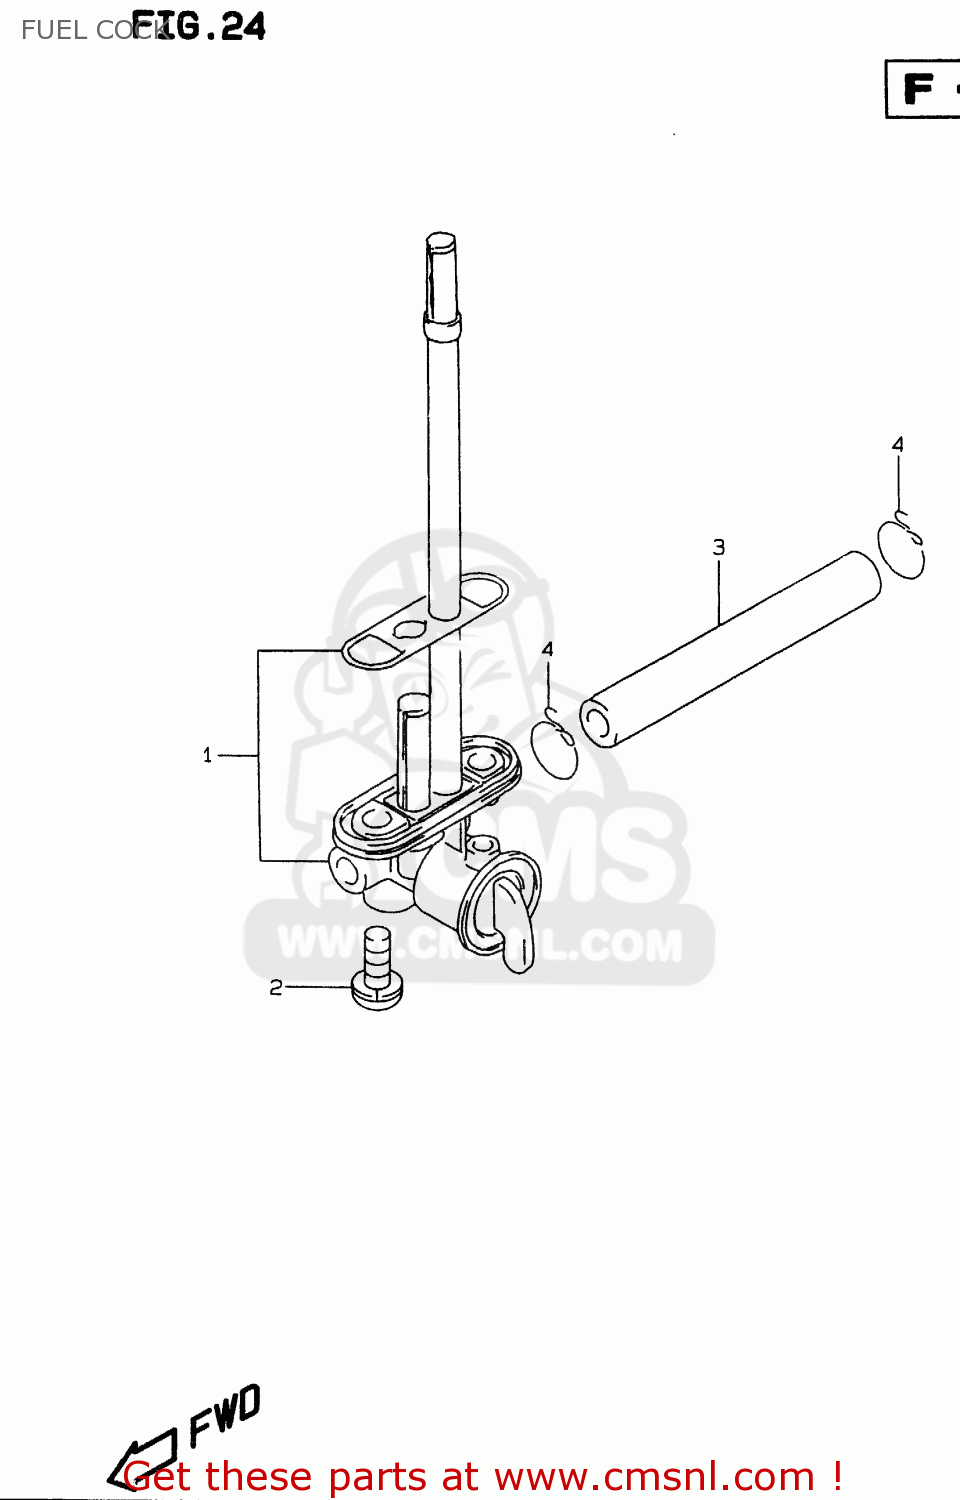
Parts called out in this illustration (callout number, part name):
1	COCK ASSY,FUEL
2	SCREW
3	HOSE,FUEL
4	CLIP
